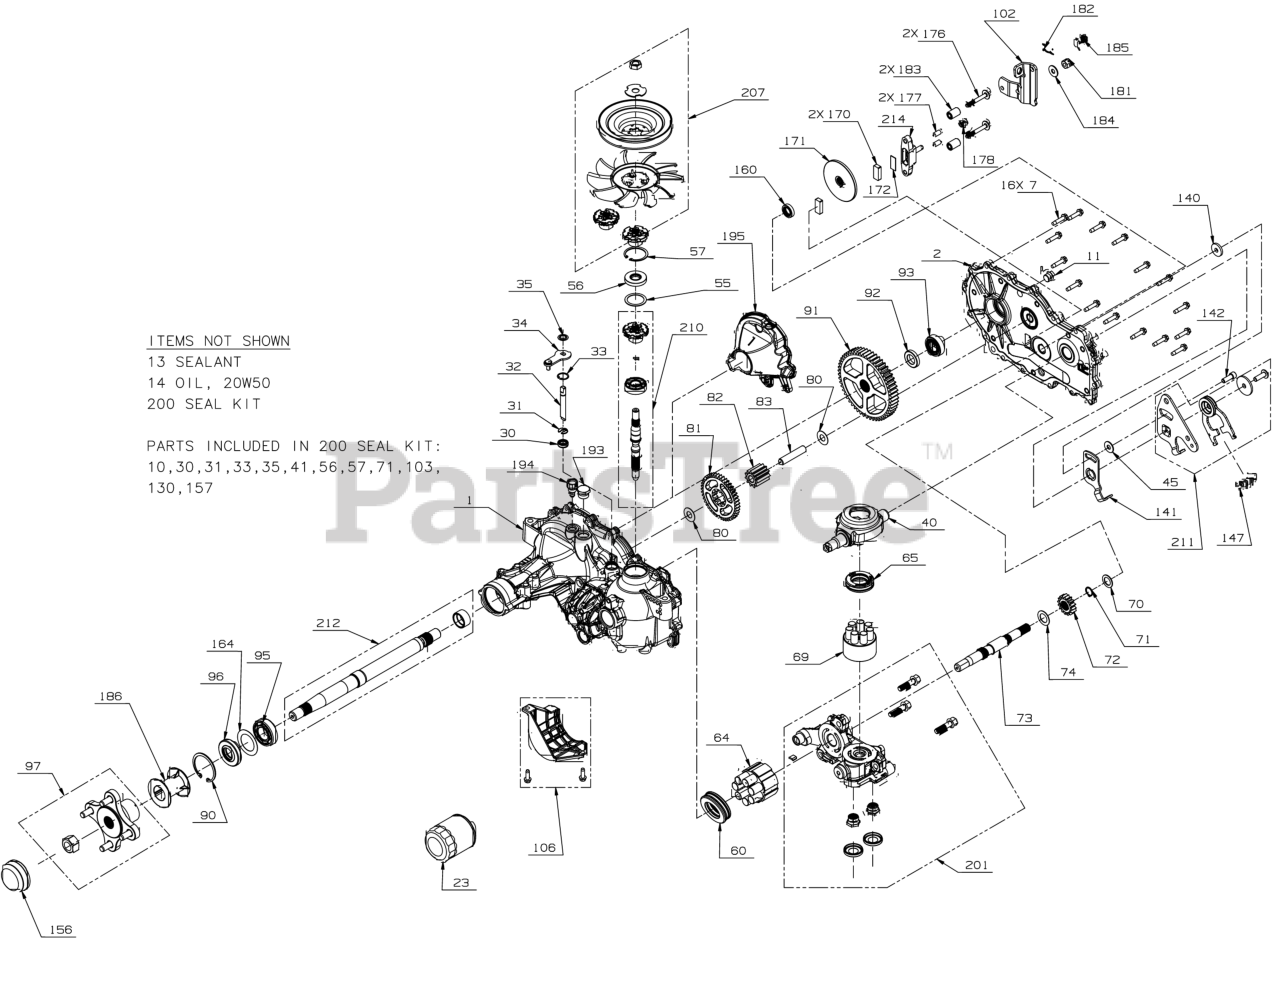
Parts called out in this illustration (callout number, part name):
1	MAIN HOUSING KIT (RH)
2	SIDE COVER KIT (RH)
7	SCREW-WASHER HEAD
11	VENT PLUG
13	SEALANT-HOUSING
23	OIL FILTER
30	SEAL-LIP .375 X .75 X .25
31	RETAINING RING
32	BYPASS RODS
33	RETAINING RING
34	ARM-BYPASS
35	RETAINING RING
40	SWASHPLATE-TRUNNION
45	FLAT WASHER
55	WASHER 1.23X1.56X
57	RETAINING RING
60	THRUST BEARING
64	CYLINDER BLOCK ASSEMBLY
65	THRUST BEARING
69	BLOCK KIT-7 PISTON
70	FLAT WASHER
71	RETAINING RING
72	GEAR-16 T
73	MOTOR SHAFT
74	MOTOR SHAFT WASHER
81	GEAR-43 T
82	GEAR-11 T
83	PIN-JACKSHAFT
90	RETAINING RING
91	GEAR-54 T
92	SPACER .75X1.32X.257
93	BALL BEARING
95	BALL BEARING
97	HUB-4 BOLT WHEEL
102	ARM-BRAKE
106	FILTER GUARD KIT
140	SPACER .32 x 1.005 x .179
141	ARM-NEUTRAL (LH)
142	SCREWS KIT-RTN
147	EXTENSION SPRING
156	COVER-NUT
170	BRAKE PUCK
171	ROTOR-BRAKE
172	PUCK PLATE
176	BOLT-SPECIAL FLANG
177	ACTUATING PIN
178	BRAKE SPRING
182	COTTER PIN-3/32 DIA x .75
183	SPACER-TORSION SPG
184	FLAT WASHER
185	BRAKE SPRING
186	TUBE-AXLE 2.03
193	PLUG 3/4-16
194	BREATHER FITTING 9/16-18
195	EXPANSION TANK (RH)
201	SECTION KIT CENTER
207	FAN & PULLEY KIT
209	PULLER KIT-HUB
210	INPUT SHAFT KIT
211	RETURN KIT-NEUTRAL (LH) ZT2800 RZT
212	SHAFT KIT-AXLE
214	BRAKE YOKE ASSEMBLY
